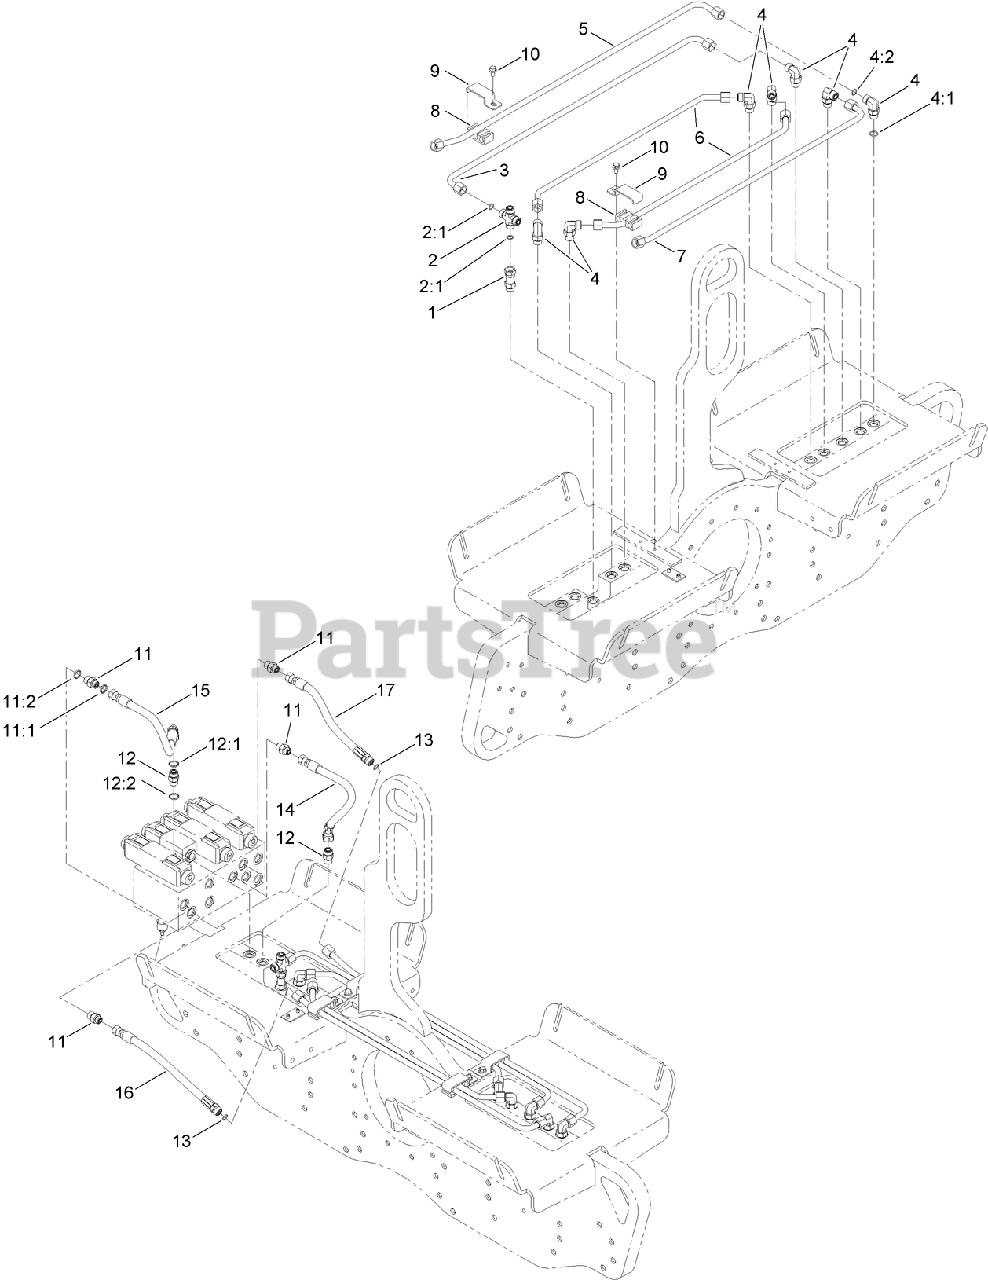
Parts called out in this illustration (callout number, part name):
1	FITTING-HYD
2	ADAPTER-HYD
2:1	O-RING
3	HYD TUBE ASM
4	FITTING-ELBOW-90 DEG
4:1	O-RING
4:2	O-RING
5	HYD TUBE ASM
6	HYD TUBE ASM
7	HYD TUBE ASM
8	TUBE-CAPTIVATOR
9	BRACKET-CAPTIVATOR, HYD
10	SCREW-HHF
11	FITTING-STRAIGHT
11:1	O-RING
11:2	O-RING
12	FITTING-STRAIGHT
12:1	O-RING
12:2	O-RING
13	O-RING
14	HOSE ASM
15	HOSE ASM
16	HOSE ASM
17	HOSE ASM
